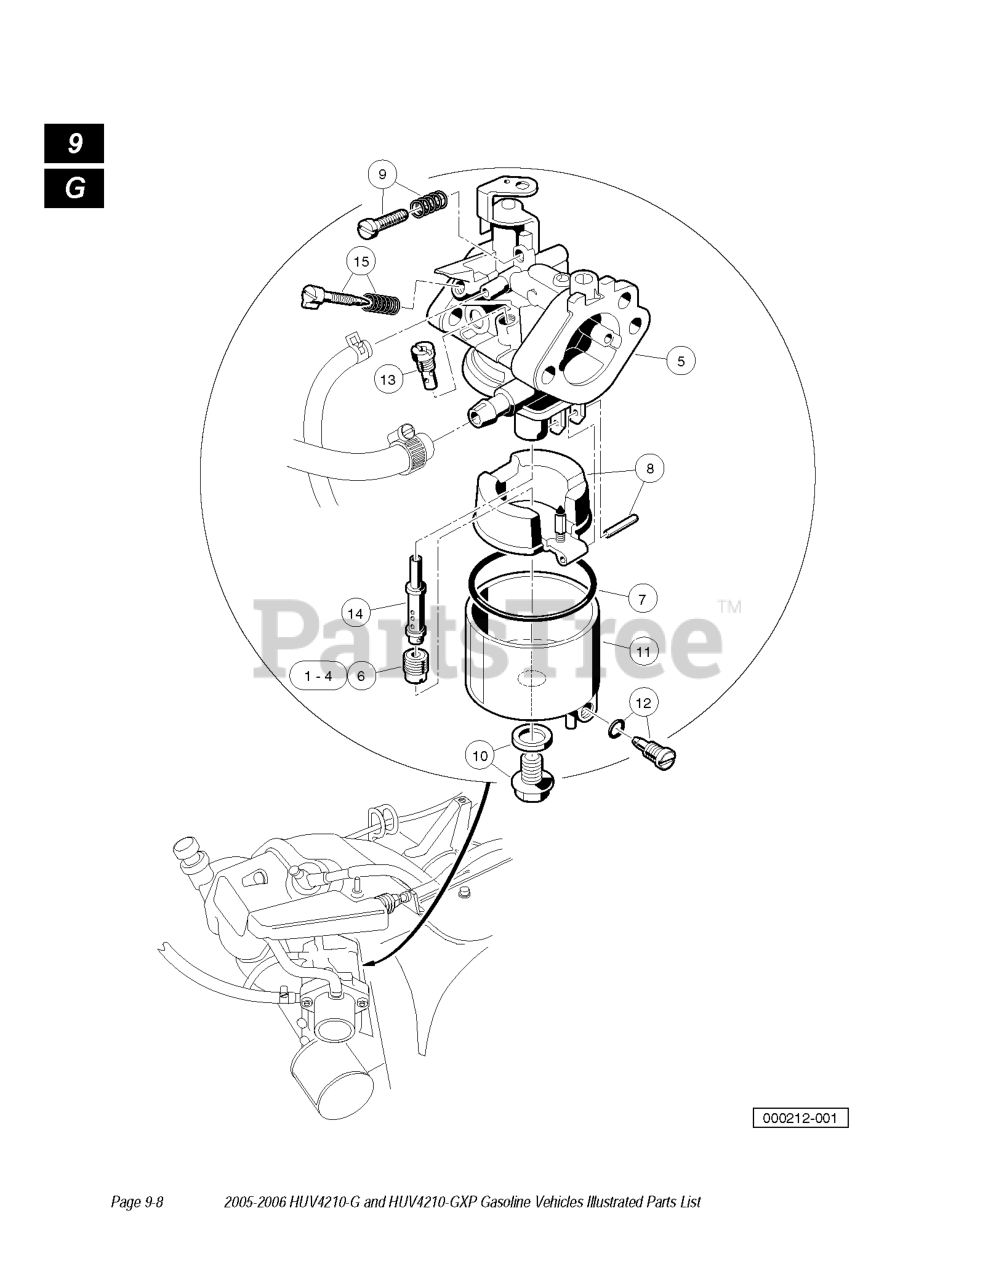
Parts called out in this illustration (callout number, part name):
1	JET, HIGH ALTITUDE OHV
2	JET, HIGH ALTITUDE OHV
3	JET, HIGH ALTITUDE JET
4	JET, HIGH ALTITUDE OHV
5	CARBURETOR ASSY, FE350D
6	HIGH ALTITUDE JET
7	GASKET, CARB. BOWL OHV
8	FLOAT ASSEMBLY
9	SCREW ASSEMBLY
11	CHAMBER ASSEMBLY - FLOAT
12	SCREW ASSEMBLY
13	JET, #40 PILOT
14	NOZZLE MAIN
